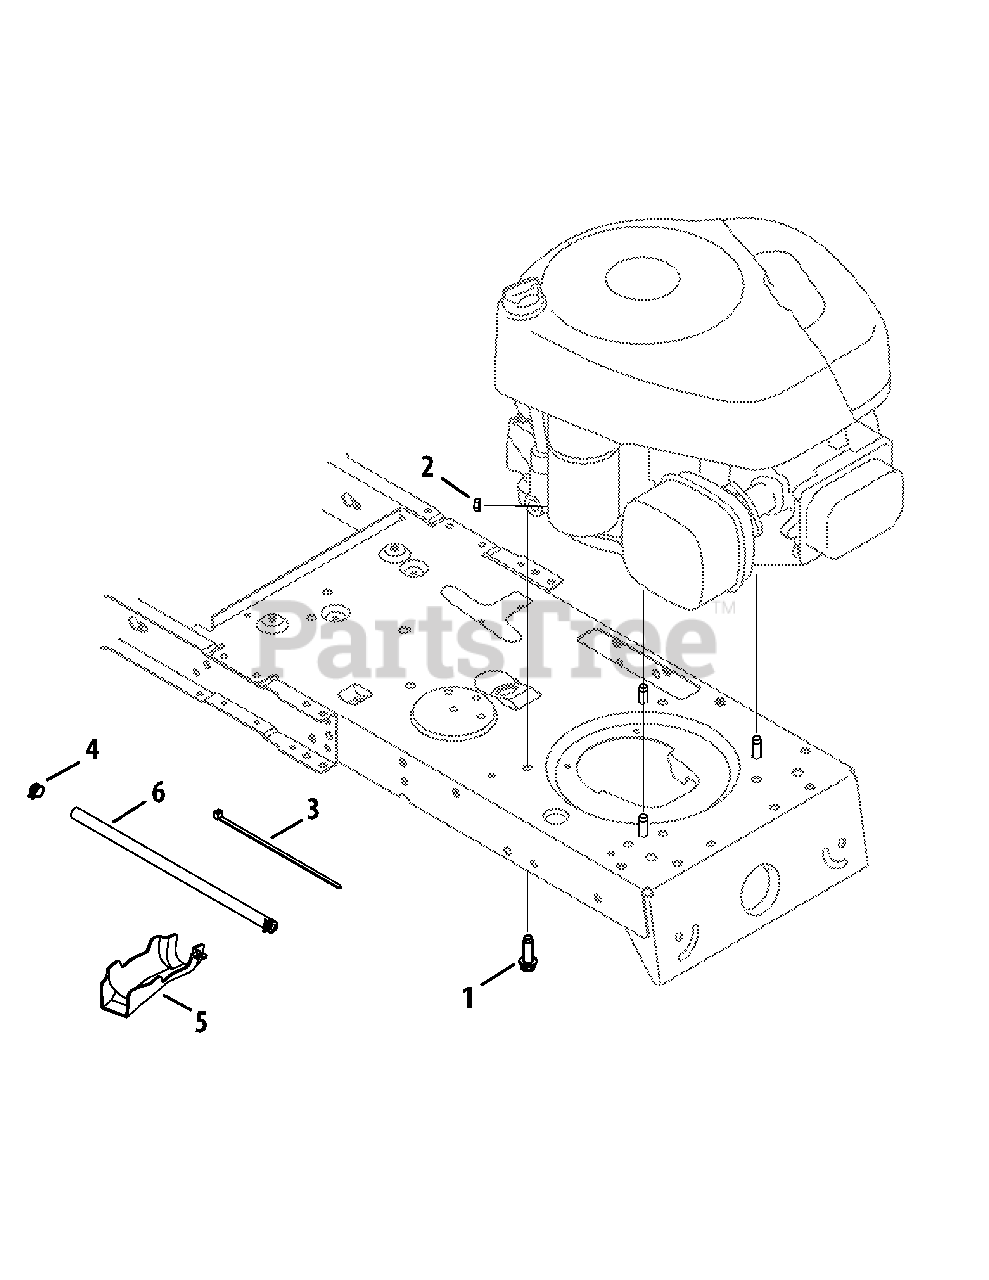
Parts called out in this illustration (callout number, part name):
1	Screw, 3/8-16 x 1.0
2	Sems Nut, 1/4-20
3	Cable Tie
4	Clamp Hose, .490 diameter
5	Oil Drain Sleeve
6	Fuel Hose, Low Permeation
